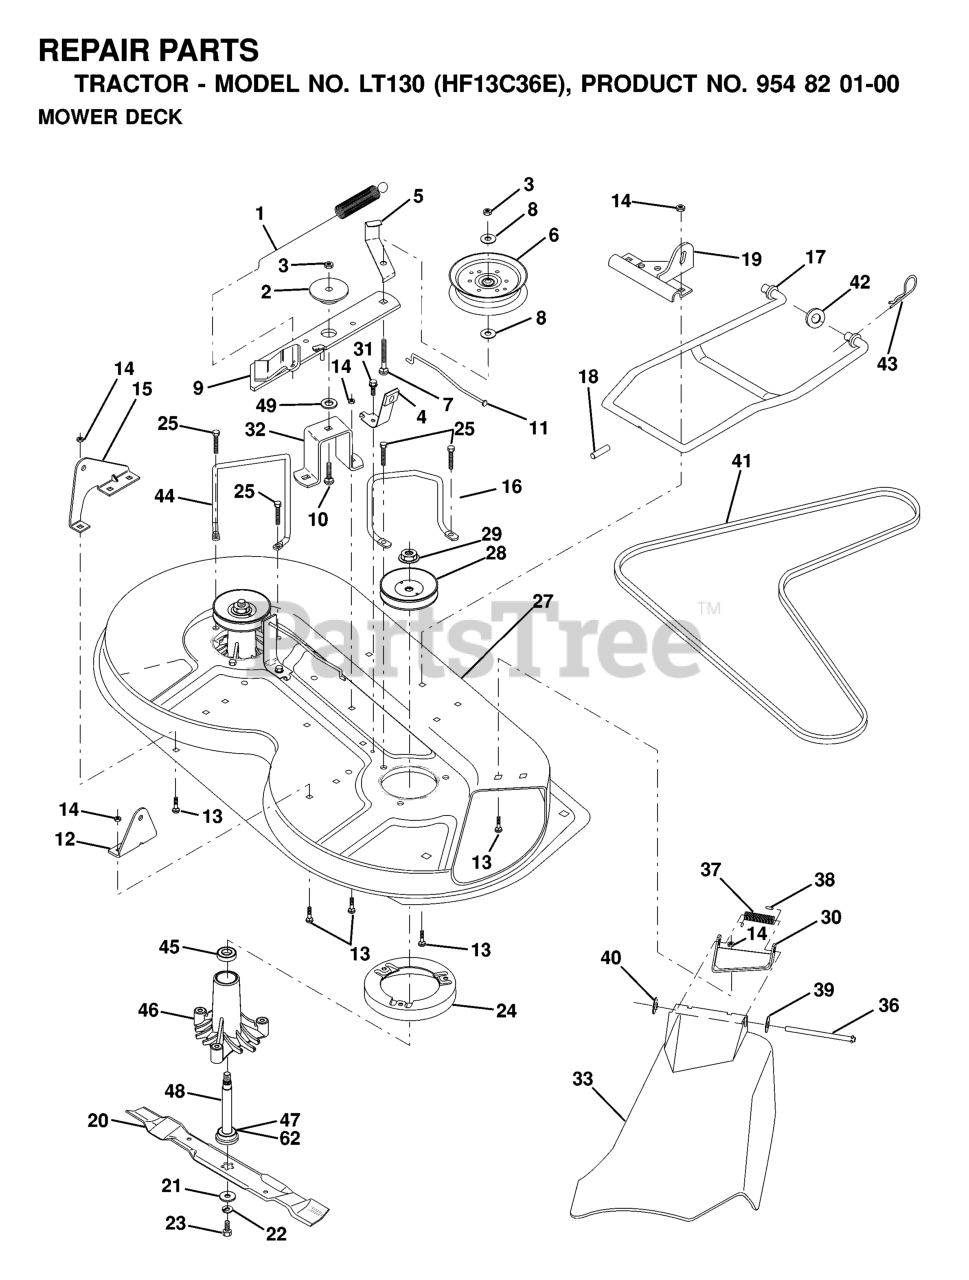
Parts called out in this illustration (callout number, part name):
1	SPRING-MOWER CLUTCH
2	SPACER.RETAINER.MOWER
4	BRAKE ASSEMBLY
5	IDLER BELT GUIDE
6	PULLEY.IDLER.FLAT.MOWER.BLK.PT
8	WASHER
9	IDLER ARM ASSY
10	BOLT.3/8-14X1.25
12	BRKT LIFT REAR
13	RP BOLT 5/16-18 X3/4 ZN/YEL GR
14	LOCKNUT
15	BRKT LIFT REAR LH
16	BELT KEEPER
17	MOWER LINK STABILIZER
18	PIN GROOVE
19	BRKT LINK STABILIIZER
20	BLADE, HI-LIFT 36" PREMIUM
21	WASHER.BLADE
22	LOCKWASHER
23	BLADE BOLT
24	STRIPPER
25	SCREW THDROL ROLLING WASHER HD
27	MOWER HOUSING
28	PULLEY, MANDREL
29	NUT
30	BRACKET ASM DEFLECTOR
31	Screw 5/16-18 x 1/2 Hex, Self Tapping 5/16-18 x 1/2
32	SUPT,IDLER ARM
36	HINGE ROD
37	SPRING TORSION
38	CAP-SLEEVE LT
39	Washer 11/32 x 5/8 x 16 Ga SD
40	NUT PUSH M
41	BELT
42	WASHER
43	SPRING RETAINER
46	HOUSING.MANDREL.VENTED (MACHD)
47	BEARING.BALL.#6204.(MANDREL)
48	SHAFT ASM VENT
49	HARDENED WASHER
62	WASHER FELT
